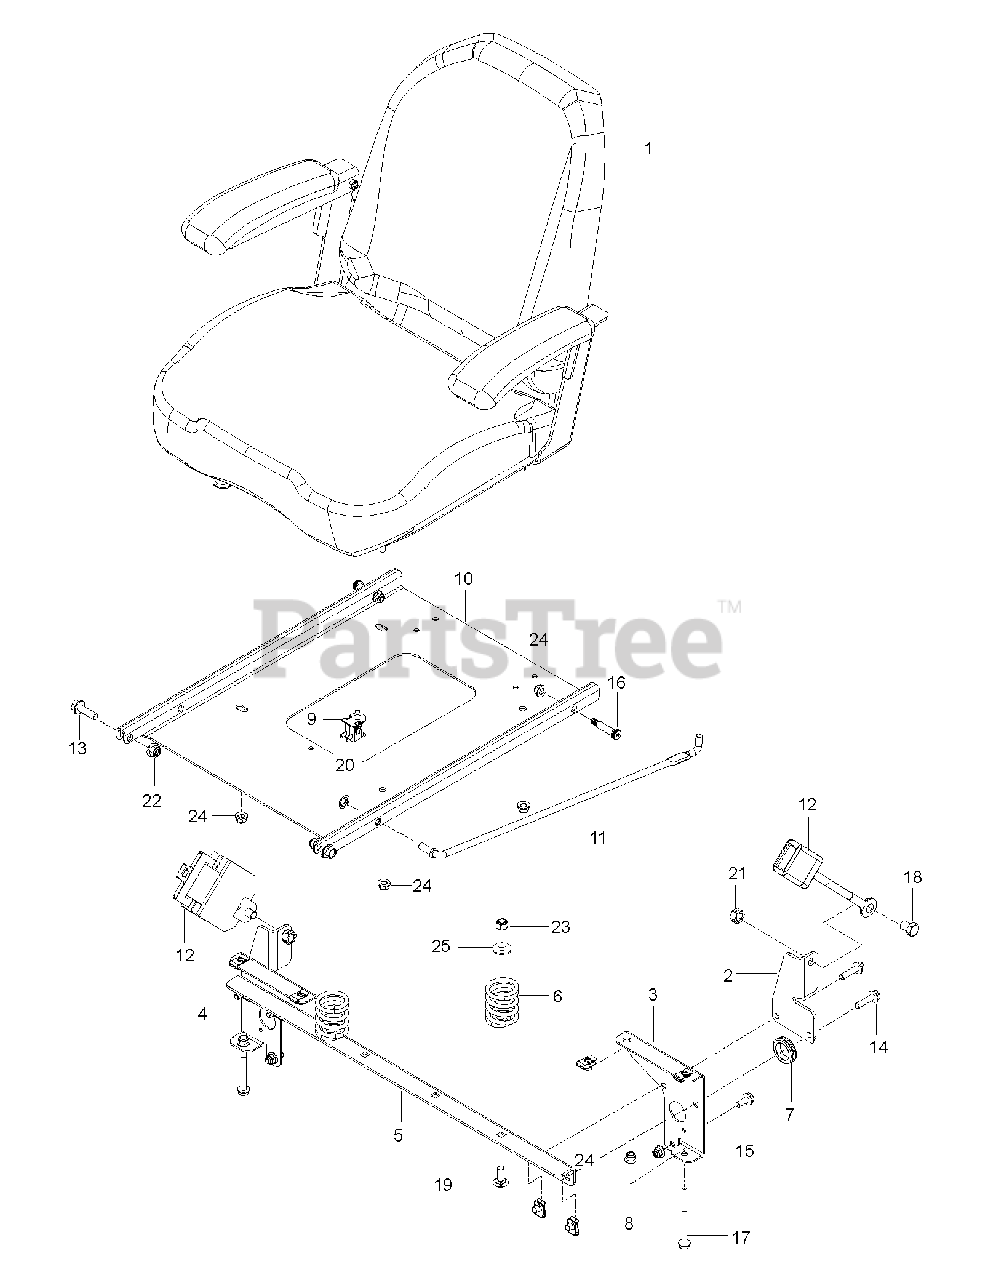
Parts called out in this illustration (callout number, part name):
1	SEAT 907 W/ SLIDE REDMAX
2	MOUNT.SEAT.BELT.BLACK
3	SUPPORT.LT.BLK
4	SUPPORT.RT.BLK
5	SUPPORT.SEAT. BLK
6	SPRING.COMPRESSION.SEAT.BLACK
7	RUBBER GROMMET
8	U-CLIP 5/16-18 NUT RETAINER
9	SWITCH.SNAPMOUNT.NC
10	PAN, SEAT, BLACK
11	ROD, SEAT
12	SEAT BELT - RETRACTABLE
13	HHFS 3/8-16 X 1.25 GD 5
14	HHFS 5/16-18 X 1.25 TPBLT GD 5
15	HHFS 5/16-18 X 3/4
16	BOLT, SHOULDER 3/8 X 1.25
17	BOLT.HEX.FLNG.5/16-18X3.75
18	HCS 7/16-20 X .75 GD 5
19	RHSNB 3/8C X 1
20	NUT 3/8 PALNUT RTNG BLK PHOS
21	NUT HEX 7/16F LOCK RP
22	NUT 3/8-16 HEX FLG NYLOC ZD
23	NUT 3/8-16 NYLOC
24	5/16-18 NYLOC FLANGE NUT
25	RP WASHER 3/8 FLAT
